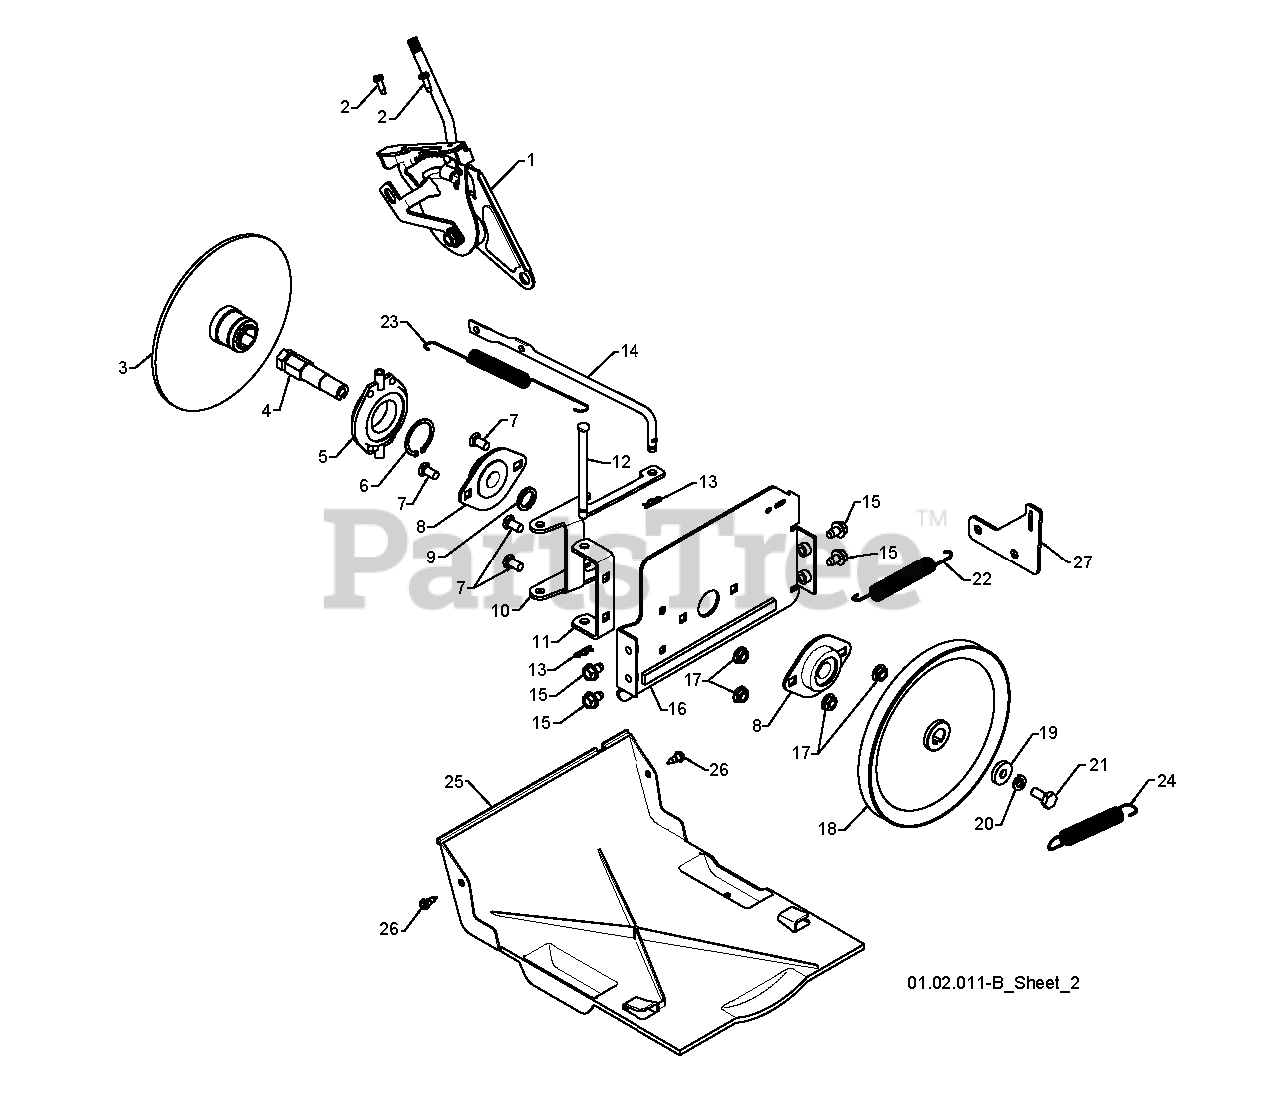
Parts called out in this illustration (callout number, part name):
1	HEAD ASSY SPEED
2	SCREW #10-24 X 5/8
3	DRIVE PLATE WELDMENT
4	SHAFT.HEX.SHORT
5	TRUNNION BEARING ASSY
6	RETAINING RING (2 2)(3 2)
7	BOLT
8	BEARING FLANGE
9	SPACER, BEARING
10	LEVER.SHIFTER.PLATE.BLACK
11	BRACKET.SHIFTER.SUPPORT.BLACK
12	PIN, PIVOT LEVER
13	RETAINER CLIP PM
14	ROD.CLUTCH.YELLOW.ZINC(VT)
15	Screw 5/16-18 x 1/2 Hex, Self Tapping 5/16-18 x 1/2
16	PLATE.DRIVE.MOUNT.BLACK
17	NUT.FLANGE.5/16
18	PULLEY.TRACTION.7.75
19	WASHER, FLAT
20	WASHER.LOCK.HVY.HLCL.SPR.5/16
21	Screw, Hex Head 5/16-18 x 3/4
22	SPRING.TRACTION.IDLER
23	SPRING.RETURN
24	SPRING, BRAKE
25	PAN.BOTTOM.PLASTIC
26	SCREW, HEX HEAD, TAPPING
27	BRACKET.TRACTION.SPRIN
